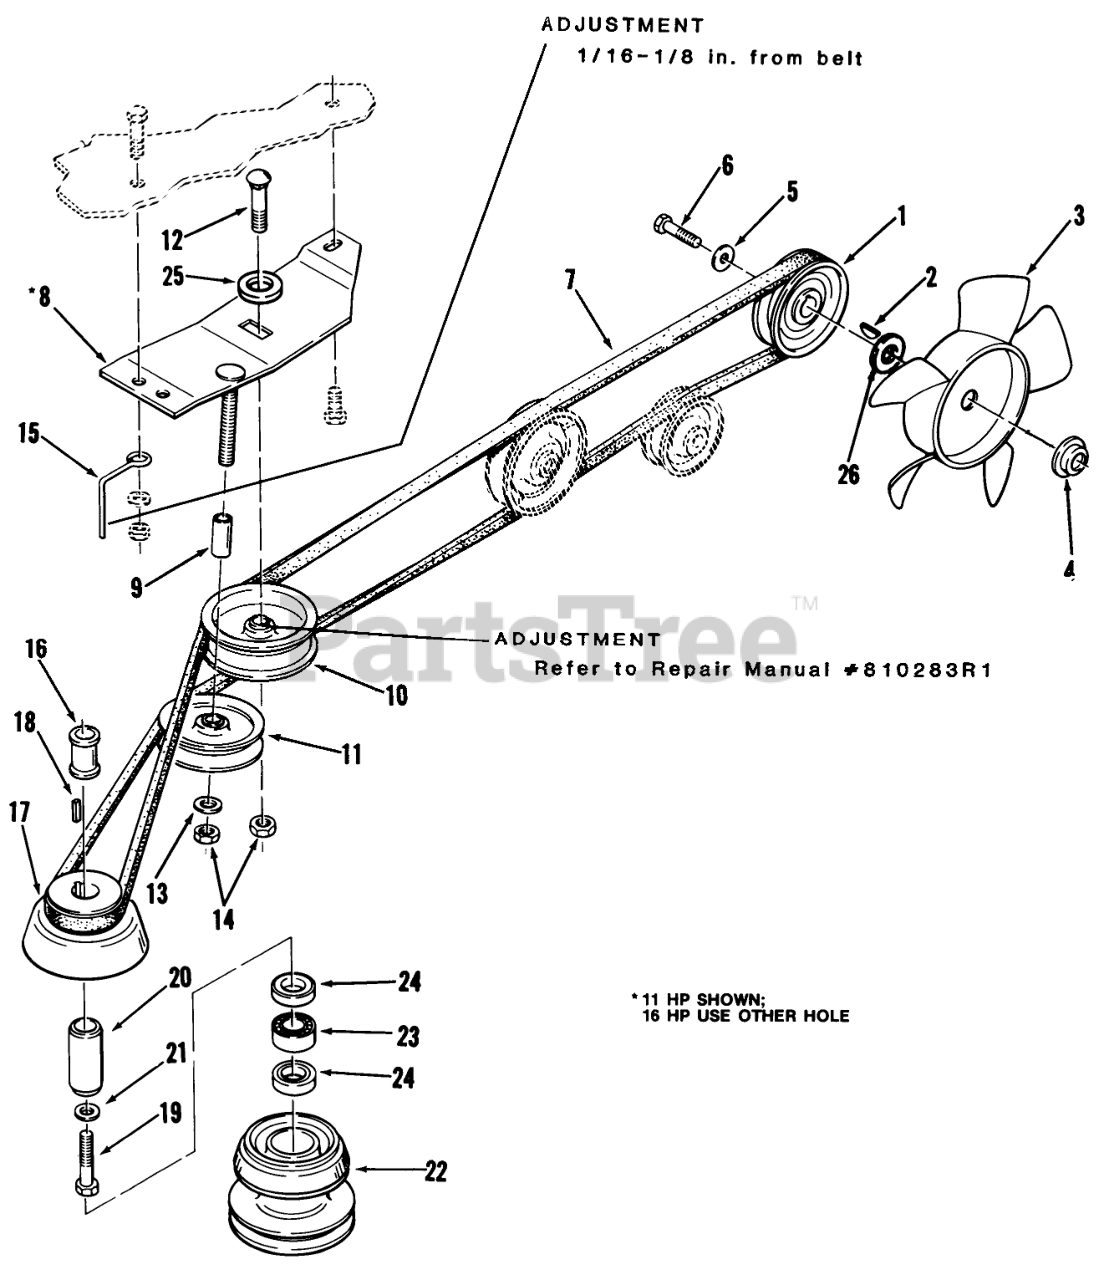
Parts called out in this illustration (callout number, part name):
1	PULLEY
2	KEY WOODR 1/8X1/2 DI
3	BLADE - FAN
4	SPACER FAN
5	WASHER
6	Bolt
7	V-BELT
7	BELT V
8	ASSY PULLEY BRACK R
9	Spacer
10	Flat Idler
11	PULLEY-IDLER STATION
12	Bolt
13	Washer
14	Nut
15	Belt Retainer
16	TUBE SPACER
17	PULLEY-ENGINE
19	HEX HD CAP SCREW
20	RACE BEARING
21	WASHER
22	Assy Pulley Mwr Dr
23	BRG-NEEDLE OPEN END
24	SEAL-OIL
25	Washer
26	Special Washer
